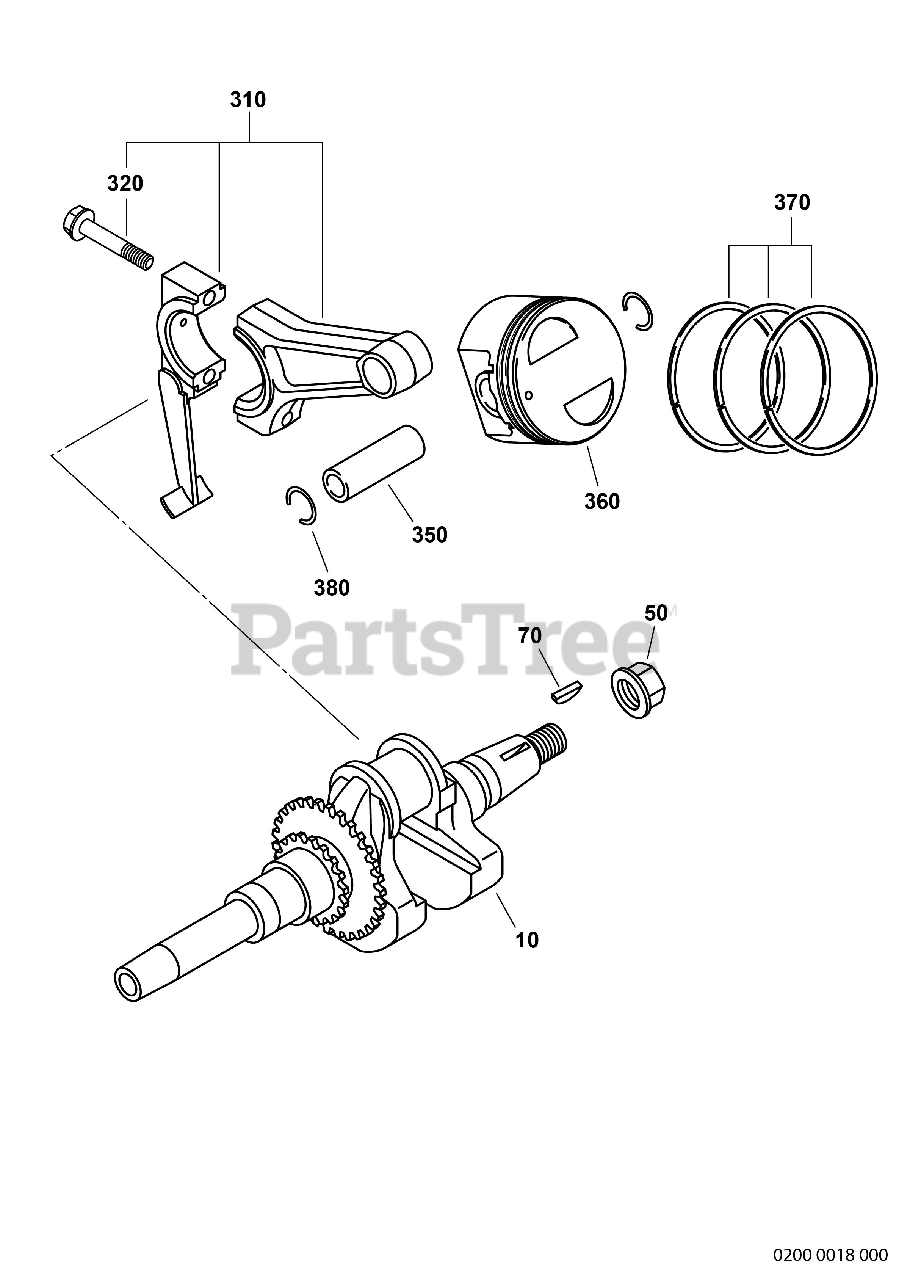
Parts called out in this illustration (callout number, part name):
50	FLANGE NUT
70	WOODRUFF KEY
310	CONNECTING ROD AY
320	CONNECTING ROD BOLT
350	PISTON PIN
360	PISTON
370	PISTON RING SET
380	CLIP
